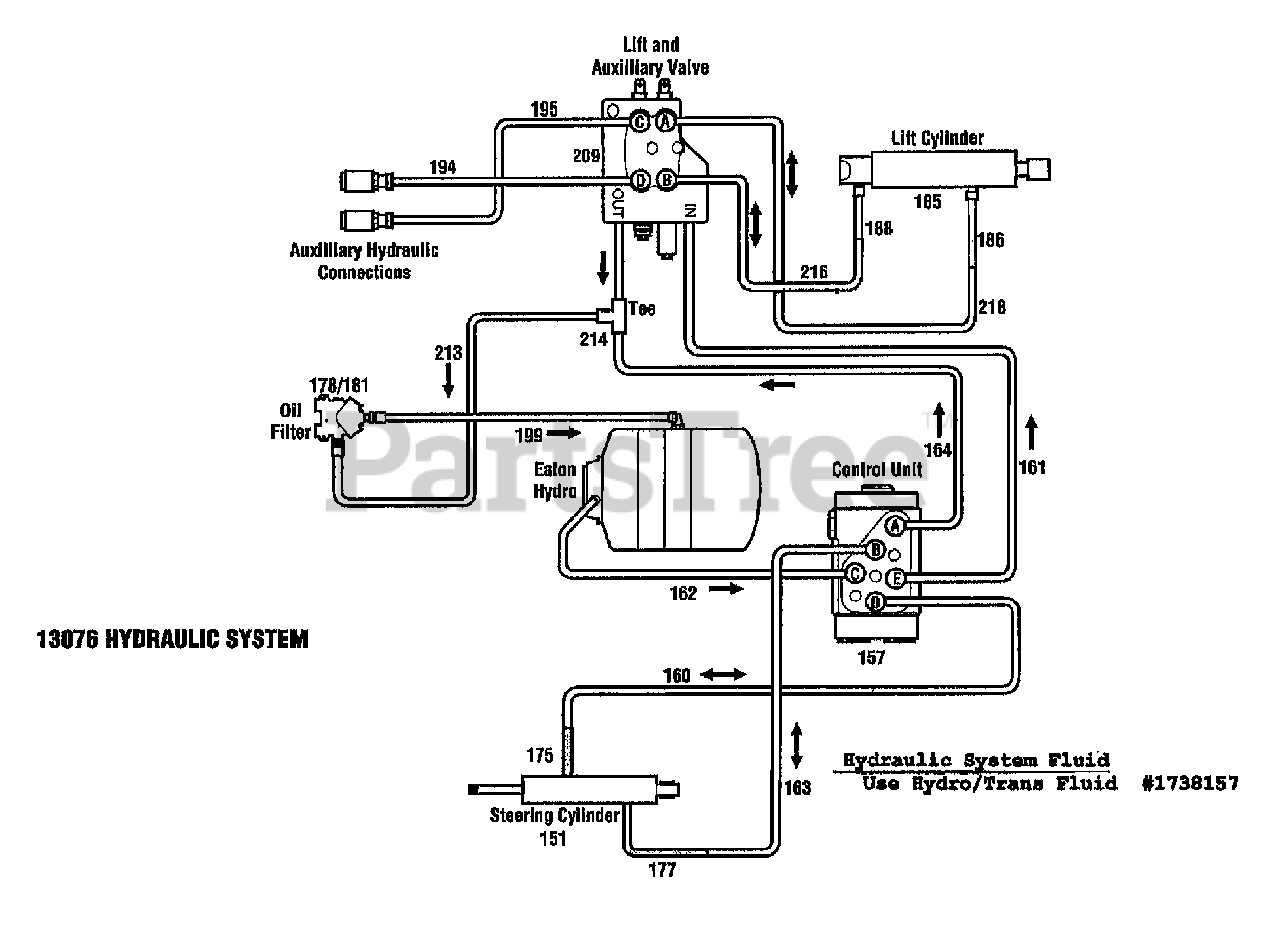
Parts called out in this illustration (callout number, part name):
151	CYLINDER-HYDRAULIC
157	CONTROL UNIT
160	TUBE-HYD RIGHT
161	TUBE-HYD PB VALVE
162	TUBE-HYDRO PRESSURE
163	TUBE-HYD LEFT
164	TUBE-HYD S C U TANK
175	ASSM-HOSE
177	ASSM-HOSE
178	FILTER-OIL
181	MANIFOLD-FILTER
185	ASSM-CYL HYDRAULIC
186	ASSM-HOSE
188	ASSM-HOSE
194	TUBE-HYD AUX-OUT
195	TUBE-HYD AUX-IN
199	ASSM-RETURN TUBE
209	VALVE-HYDRAULIC
213	TUBE-HYD RETURN
214	TEE-SWIVEL
216	TUBE-HYD VALVE TO ROD
218	TUBE-HYD VALVE TO HEAD
